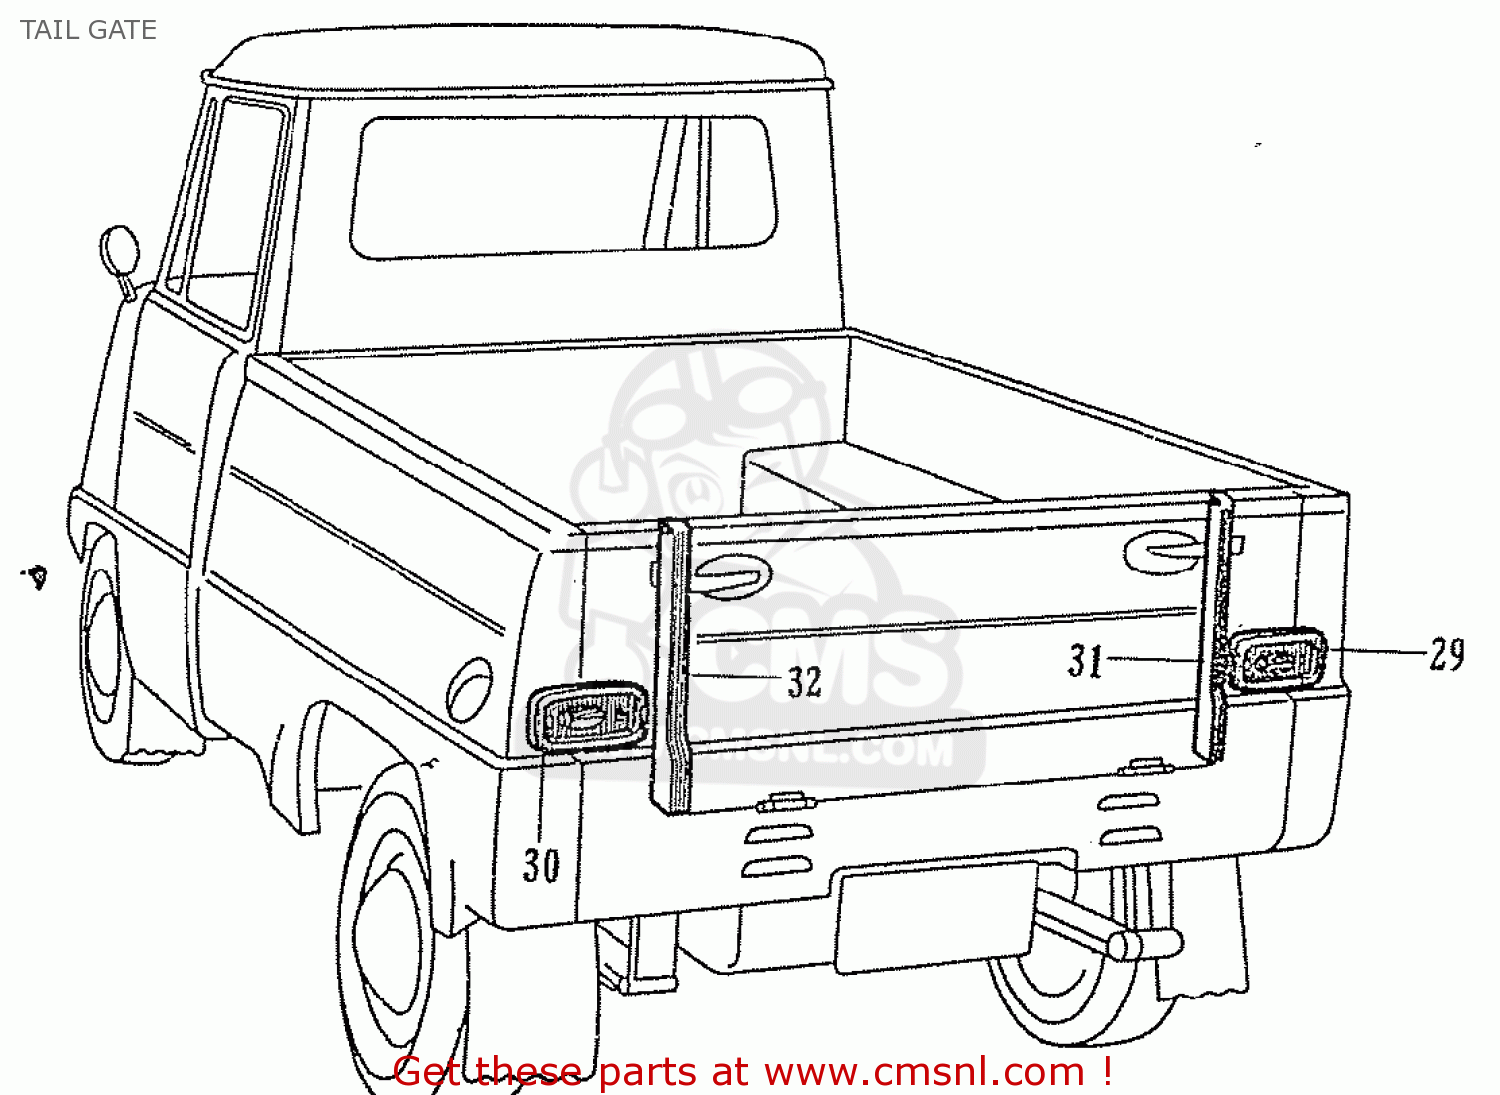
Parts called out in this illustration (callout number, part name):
29	SOCKET, RIGHT BASE
30	SOCKET, LEFT BASE
31	FRAME, RIGHT TAIL GATE
32	FRAME, LEFT TAIL GATE
